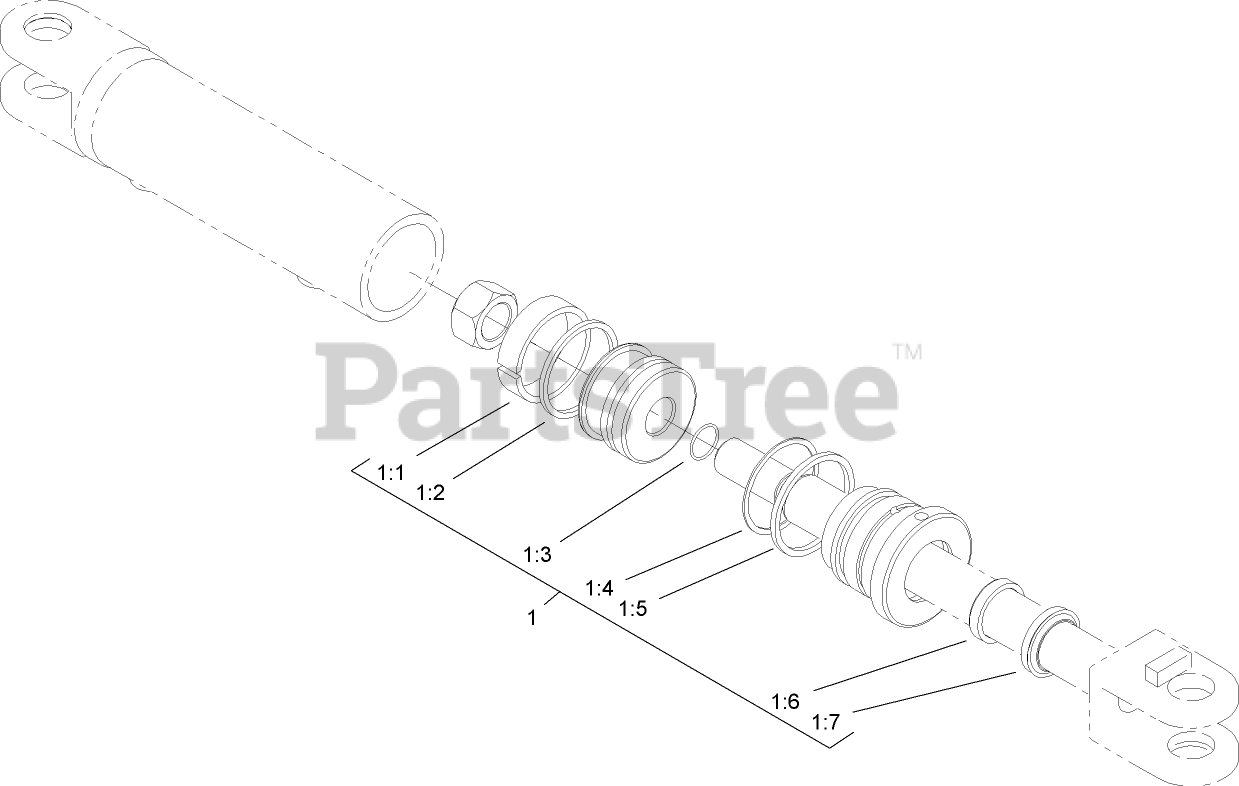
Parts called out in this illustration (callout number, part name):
1	KIT-SEAL, CYLINDER
1:1	Ring-Wear (Not serviced separately)
1:2	Seal-Psp (Not serviced separately)
1:3	O-RING (Not serviced separately)
1:4	O-RING (Not serviced separately)
1:5	Washer-Backup (Not serviced separately)
1:6	Polypak (Not serviced separately)
1:7	Wiper-Rod (Not serviced separately)
